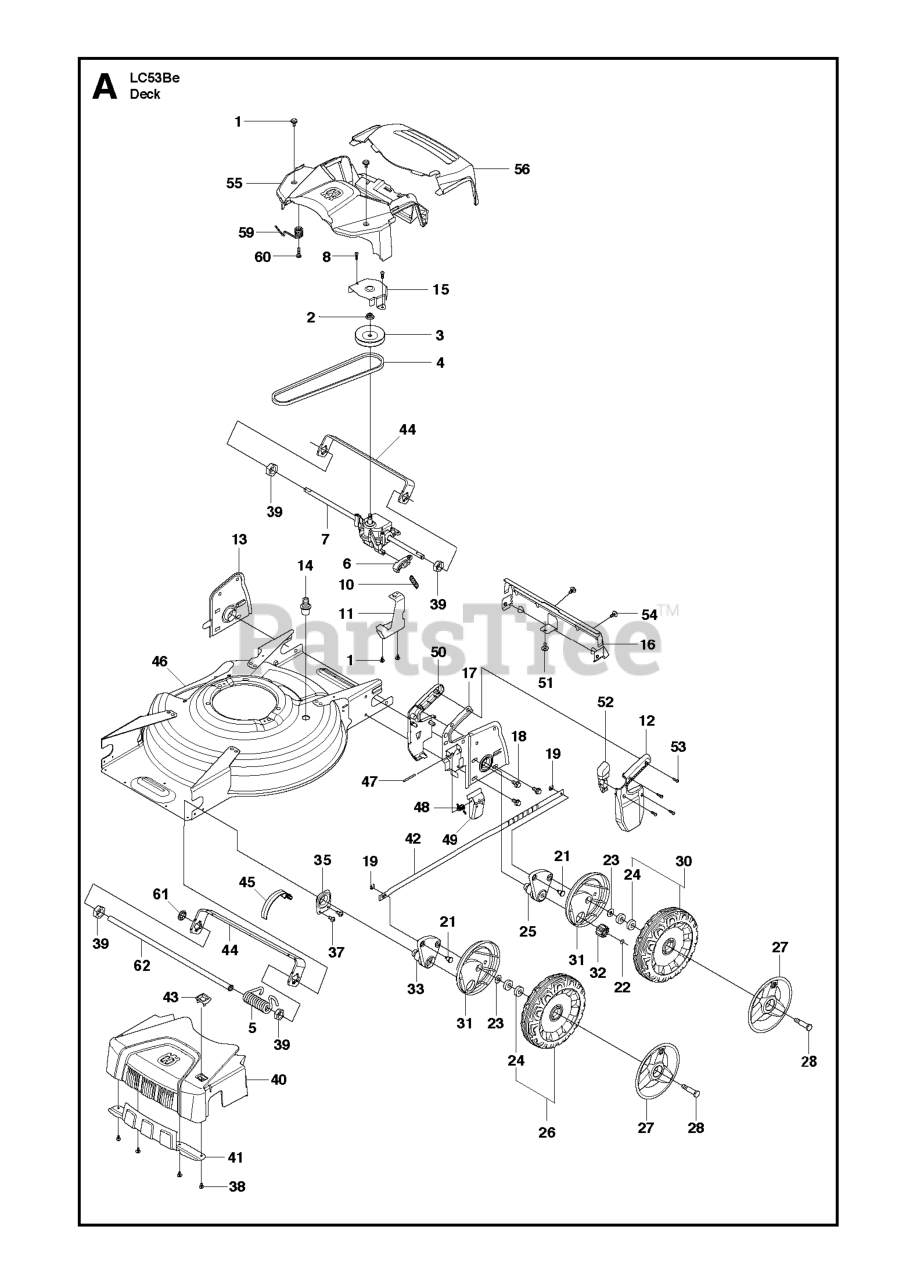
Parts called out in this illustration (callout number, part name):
1	SCREW ITXPANTT M5X10 ZPB (A00
4	BELT WRAPPED V-BELT Z 31 3/4"
8	SCREW ITXPANT T50X16 ZN/FE (A
19	FASTENER
24	BALL BEARING
37	SCREW ITXPANTT M5X10 ZPB (A00
38	SCREW ITXPANTT M5X10 ZPB (A00
51	SCREW ITXPANTT M5X10 ZPB (A00
53	SCREW ITXPANT T50X16 ZN/FE (A
54	SCREW ITXPANTT M5X10 ZPB (A00
57	SCREW ITXPANTT M5X10 ZPB (A00
60	SCREW ITXPANT T50X16 ZN/FE (A
